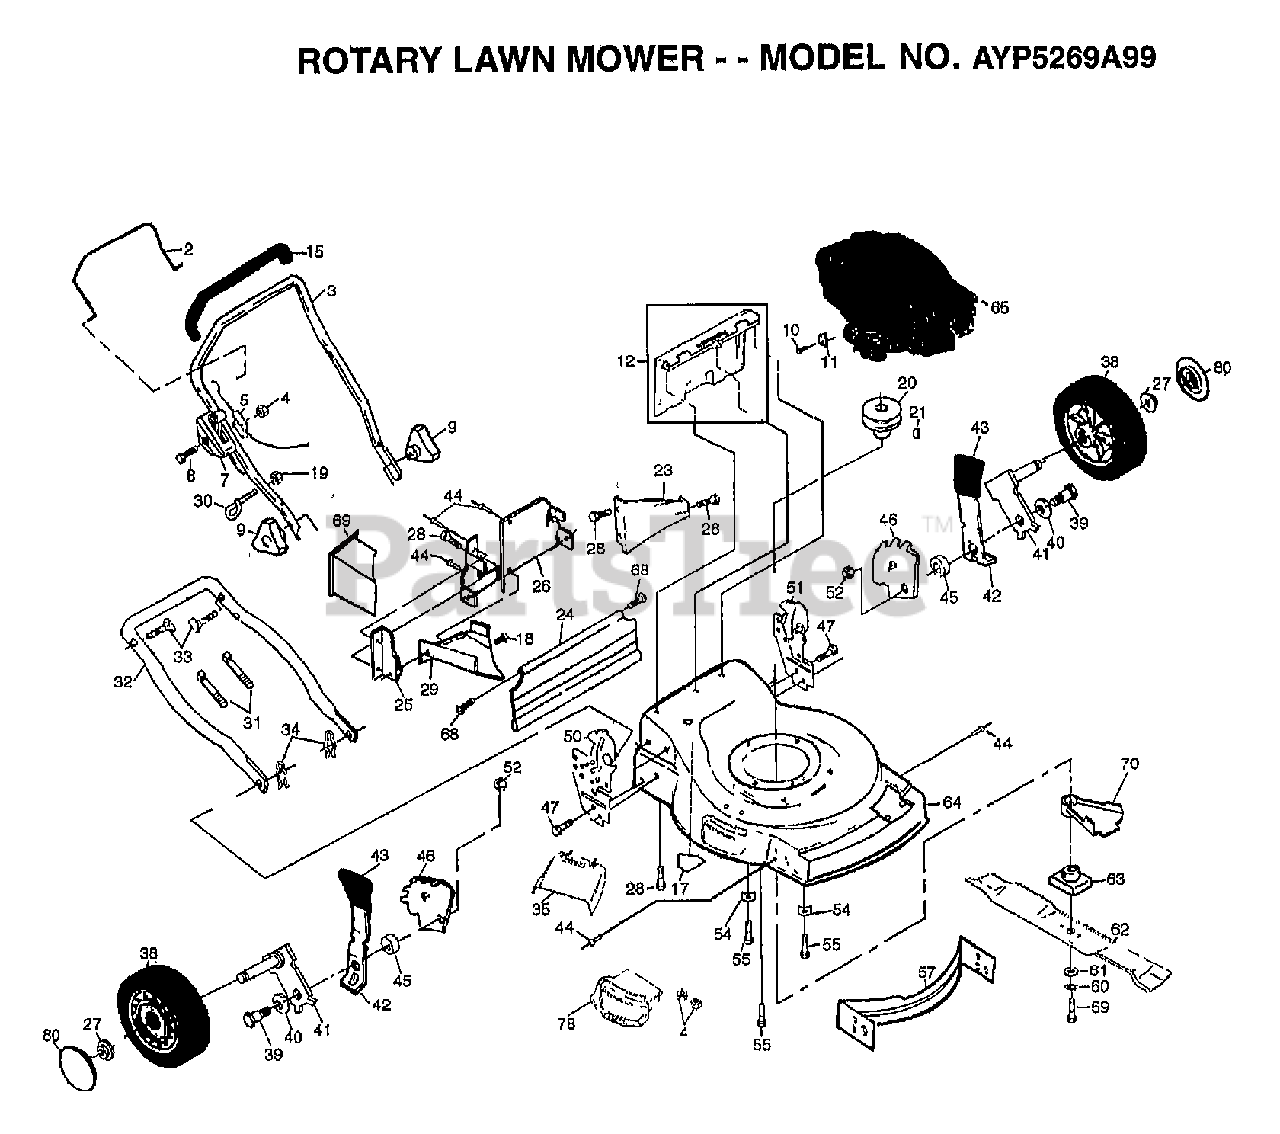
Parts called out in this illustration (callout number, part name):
2	BAIL.CNTRL.SRD.CM
3	HANDLE.UPPER.STD.
5	"CABLE,ENG ZONE CO"
7	"CONTROL, THROTTLE"
8	SCREW.HXHD.WASH.
9	KNOB PM
10	SCREW PM
11	CABLE CLAMP
12	KIT.DOOR.REAR
15	GRIP.HANDLE.FOAM
17	DECAL-DANGER PM
18	SCREW.HXTAP.10-24
20	ENGINE.PULLEY.FWG
21	HI PRO KEY PM
23	REAR BAFFLE
24	SKIRT.REAR.FGD.22
27	HEX FLANGE LOCKNT
28	SCREW
29	DISCHARGE BAFFLE
30	ROPE GUIDE
32	HANDLE LOWER
33	BOLT.HANDLE.LM
34	HAIRPIN COTTER
35	GUARD.DISCH.CLIPO
38	WHEEL.8X2.PR.RAD.
39	BOLT SHLD 3/8-16
40	"WASHER, BELLEVIL."
41	ARM.AXLE.ASM.BZP.
42	SPRING SELECTOR
43	KNOB PM
44	BLIND RIVET
45	SPACER.HEIGHT.ADJ
46	BRACKET.ADJ.9.LH
47	SCREW.HXWS.5/16
50	BRACKET.HDL.RH.
51	BRACKET.HDL.LH.
52	LOCKNUT PM
55	BOLT.ENG.3/8-16
57	KIT.BAF.FRT.22RD
59	SCREW
60	LOCKWASHER
61	"WASHER,HARDEN"
62	"BLADE.MULCH.22"""
63	ADAPTOR.BLADE.LM
64	LAWNMOWER HOUSING KIT
68	HINGE SCREW
69	PLUG.MULCH.22RD
78	KIT.DOOR.MUL.CO
80	HUB CAP
